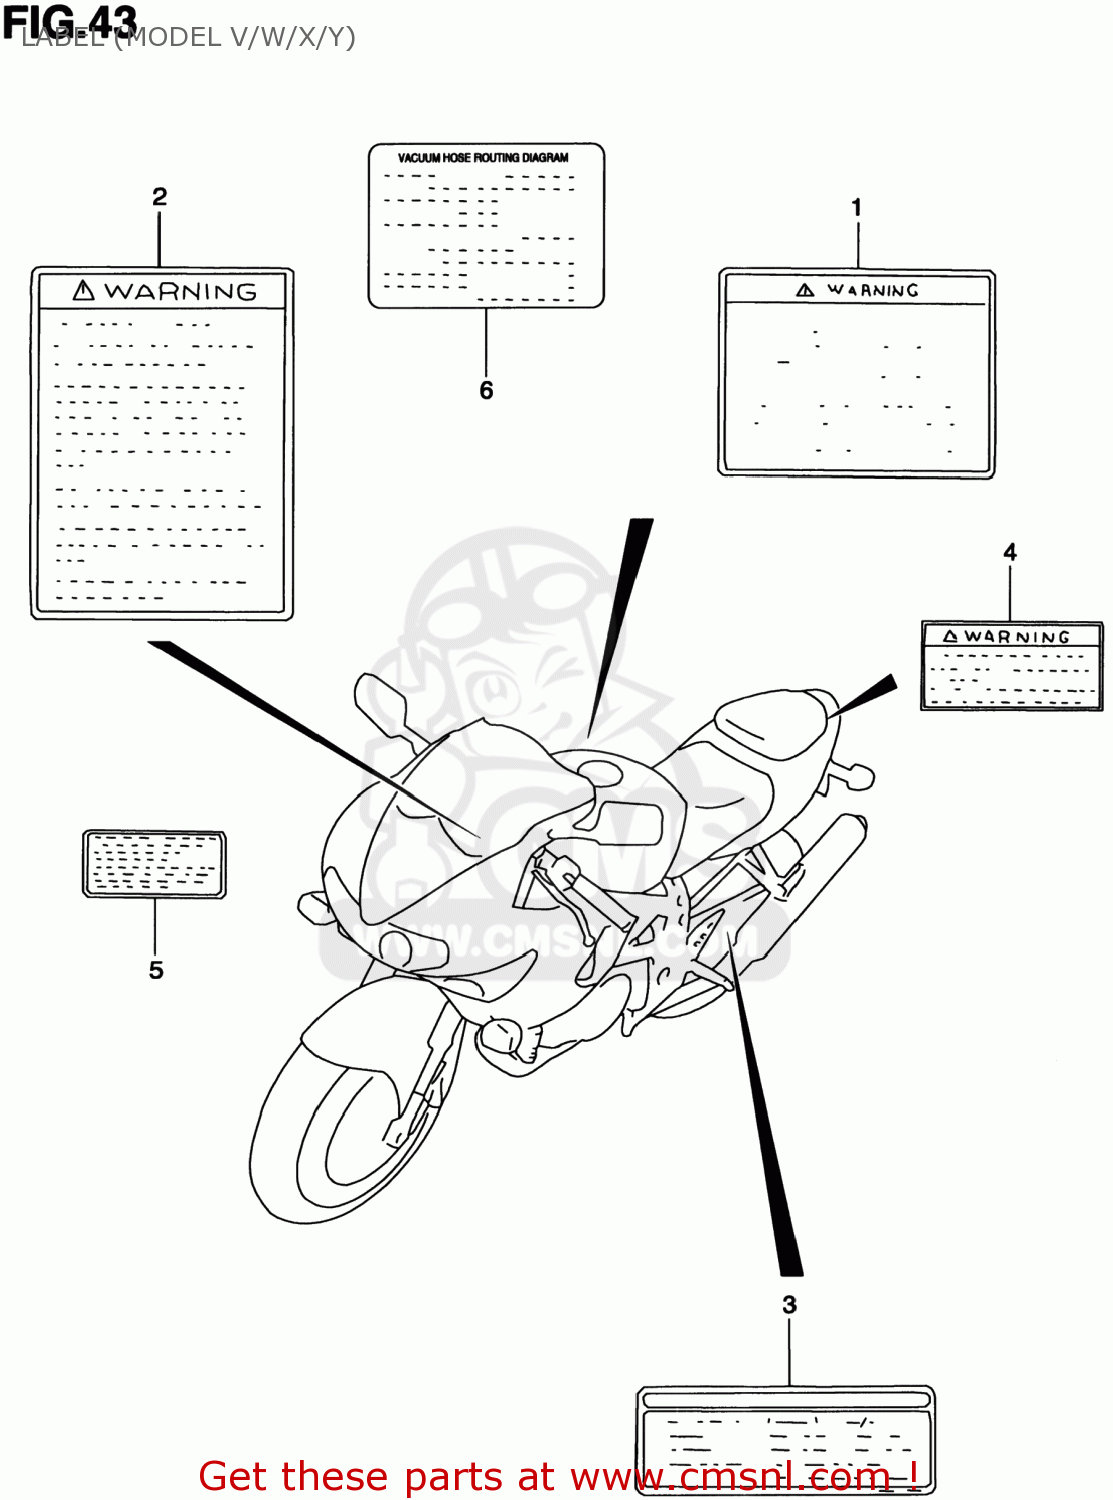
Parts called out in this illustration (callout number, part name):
1	LABEL,GENERAL WARNING
2	LABEL,WARNING SCREEN
3	LABEL,TIRE INFORMATION
4	LABEL (MANUAL NOTICE)
5	LABEL,WARNING STEERING
6	LABEL (VACUUM HOSE ROUTING)
7	MANUAL, OWNER'S
